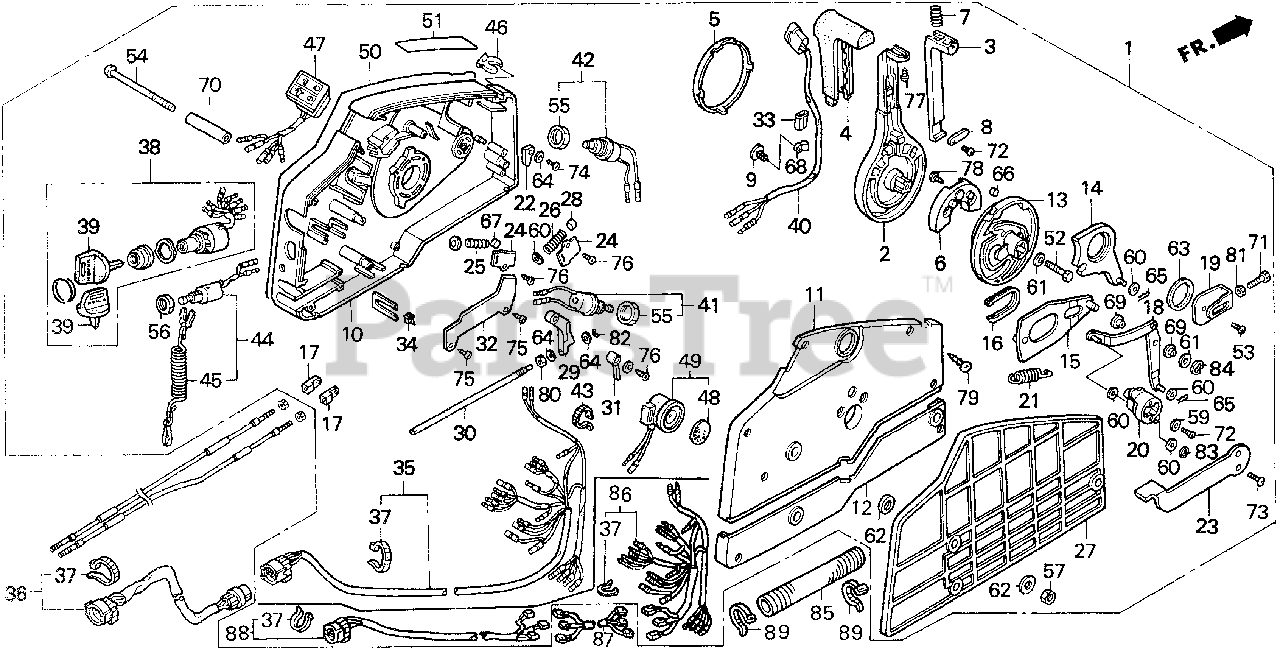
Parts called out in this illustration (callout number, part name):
1	BOX ASSY., REMOTE CONTROL (P/T)
1	BOX ASSY., REMOTE CONTROL
2	HANDLE, REMOTE CONTROL
3	LEVER, HANDLE LOCK
4	GRIP, REMOTE CONTROL HANDLE
5	CAP, HANDLE
6	BLOCK, NEUTRAL LOCK
7	SPRING, REMOTE CONTROL HANDLE
8	PLATE, LEVER SETTING
9	CLAMP, HARNESS
10	HOUSING, REMOTE CONTROL BOX (A)
11	HOUSING, REMOTE CONTROL BOX (B)
12	HOUSING, REMOTE CONTROL BOX (C)
13	WHEEL, CONTROL
14	ARM, SHIFT LINK
15	PLATE, SLIDING
16	COLLAR, SLIDING PLATE
17	PIVOT, SHIFT
18	ARM, LINK JOINT
19	BRACKET, LINK JOINT
20	WHEEL, ACCELERATOR
21	SPRING, ACCELERATOR WHEEL
22	CAM, STARTER SWITCH
23	LEVER, IDLE
24	PLATE, SPRING SETTING
25	SPRING, SHIFT CLICK
26	SPRING, CHOKE RETURN
27	SPACER, REMOTE CONTROL BOX
28	SPACER, CLICK SPRING
29	BLOCK, THROTTLE FRICTION
30	BOLT, FRICTION
31	SPACER, NEUTRAL SWITCH
32	CLAMP, POWER TILT CORD
33	PIPE, HARNESS GUIDE
34	SPACER, CABLE CLAMP
37	TIE, CABLE
38	SWITCH ASSY., COMBINATION
39	KEY ASSY., COMBINATION SWITCH
40	SWITCH ASSY., POWER TRIM-TILT
41	SWITCH ASSY., THROTTLE
42	SWITCH ASSY., SOLENOID
44	SWITCH ASSY., EMERGENCY STOP
45	WIRE, EMERGENCY
46	CLIP, EMERGENCY LOCK
47	LAMP ASSY., INDICATOR
48	PLATE, TURN SIGNAL BUZZER
49	BUZZER, WARNING
50	PLATE, REMOTE CONTROL
51	MARK, FAST IDLE
52	BOLT, HEX. (8X35)
53	SCREW, PAN (6X10)
54	SCREW (6X95)
55	NUT, HEX. (20MM)
56	NUT, HEX. (16MM)
57	NUT, HEX. (6MM)
59	WASHER, PLAIN (5MM)
60	WASHER, PLAIN (6MM)
61	WASHER, PLAIN (8MM)
62	WASHER (6MM)
63	WASHER (28MM)
64	WASHER, PLAIN (4MM)
65	PIN, LOCK (6MM)
67	ROLLER, CLICK
68	CLIP, WIRE HARNESS
69	COLLAR, LINK JOINT
70	COLLAR, DISTANCE (6X10X43.5)
71	BOLT, HEX. (5X16)
72	SCREW, PAN (5X10)
73	SCREW, OVAL (5X12)
74	SCREW, TAPPING (4X10)
75	SCREW, TAPPING (5X8)
76	SCREW, TAPPING (5X10)
77	SCREW, TAPPING (5X12)
78	SCREW, TAPPING (6X16)
79	SCREW, TAPPING (5X25)
80	NUT, HEX. (6MM)
81	NUT, HEX. (5MM)
82	E-RING (3MM)
83	E-RING (4MM)
84	E-RING (7MM)
85	TUBE, CORRUGATED (28MM)
86	CABLE ASSY., REMOTE CONTROL (B)
87	CABLE ASSY., REMOTE CONTROL EXTENSION
88	CABLE (14WIRE) (16.5')
89	BAND, SELF-LOCK
